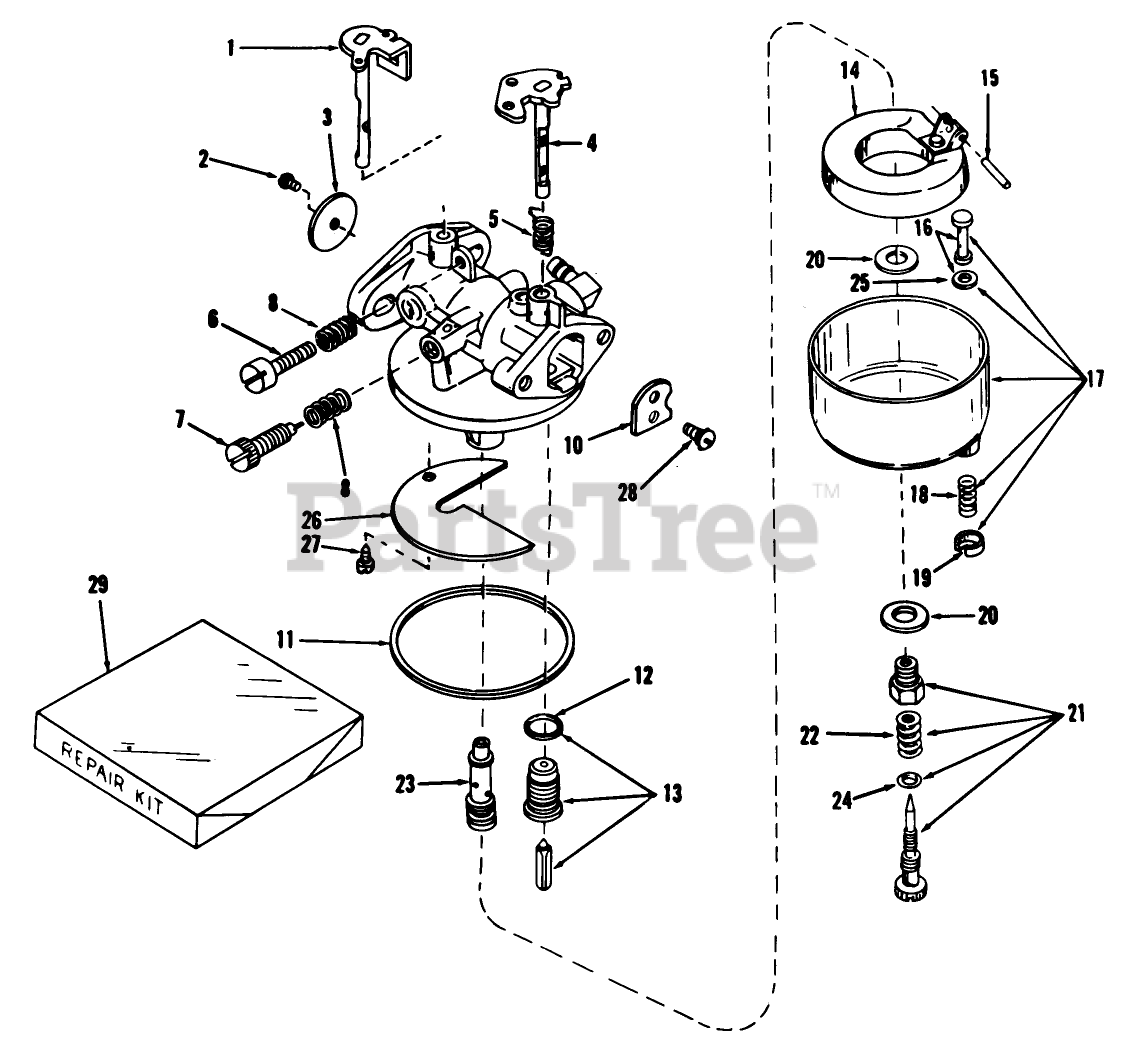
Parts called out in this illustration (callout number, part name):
16	Plunger Assy., Drain (Incl. Ref. 18)
18	Spring, Drain Plunger
19	Retainer, Plunger Spring
20	Washer-Bowl Nut
25	Gasket-Plunger, Drain
